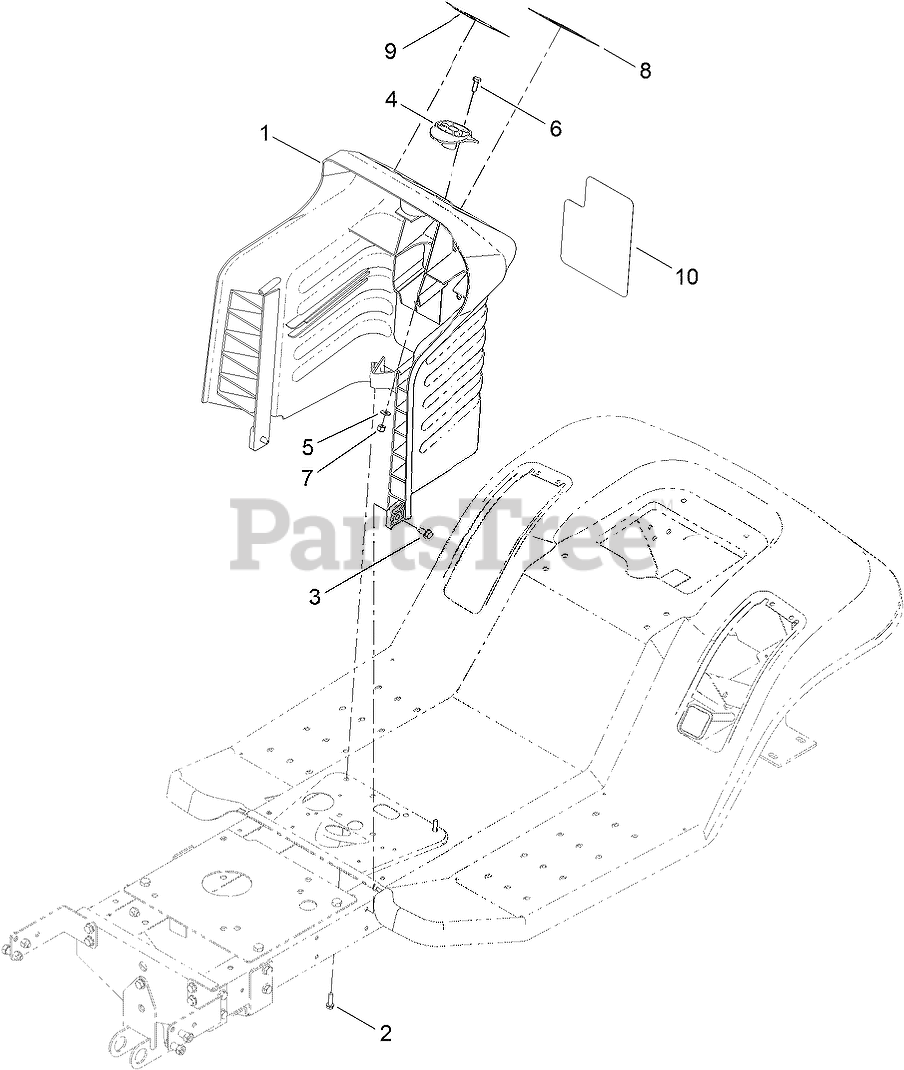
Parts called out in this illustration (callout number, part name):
1	TOWER-STEERING
2	SCREW-HWH
3	SCREW-HWH
4	BUSHING-SLIDING
5	WASHER-FLAT
6	SCREW-HH
7	NUT-LOCK, NI
8	DECAL-THROTTLE
9	DECAL-IGNITION/LIGHTS
10	DECAL-WARNING, INSTRUCTION
